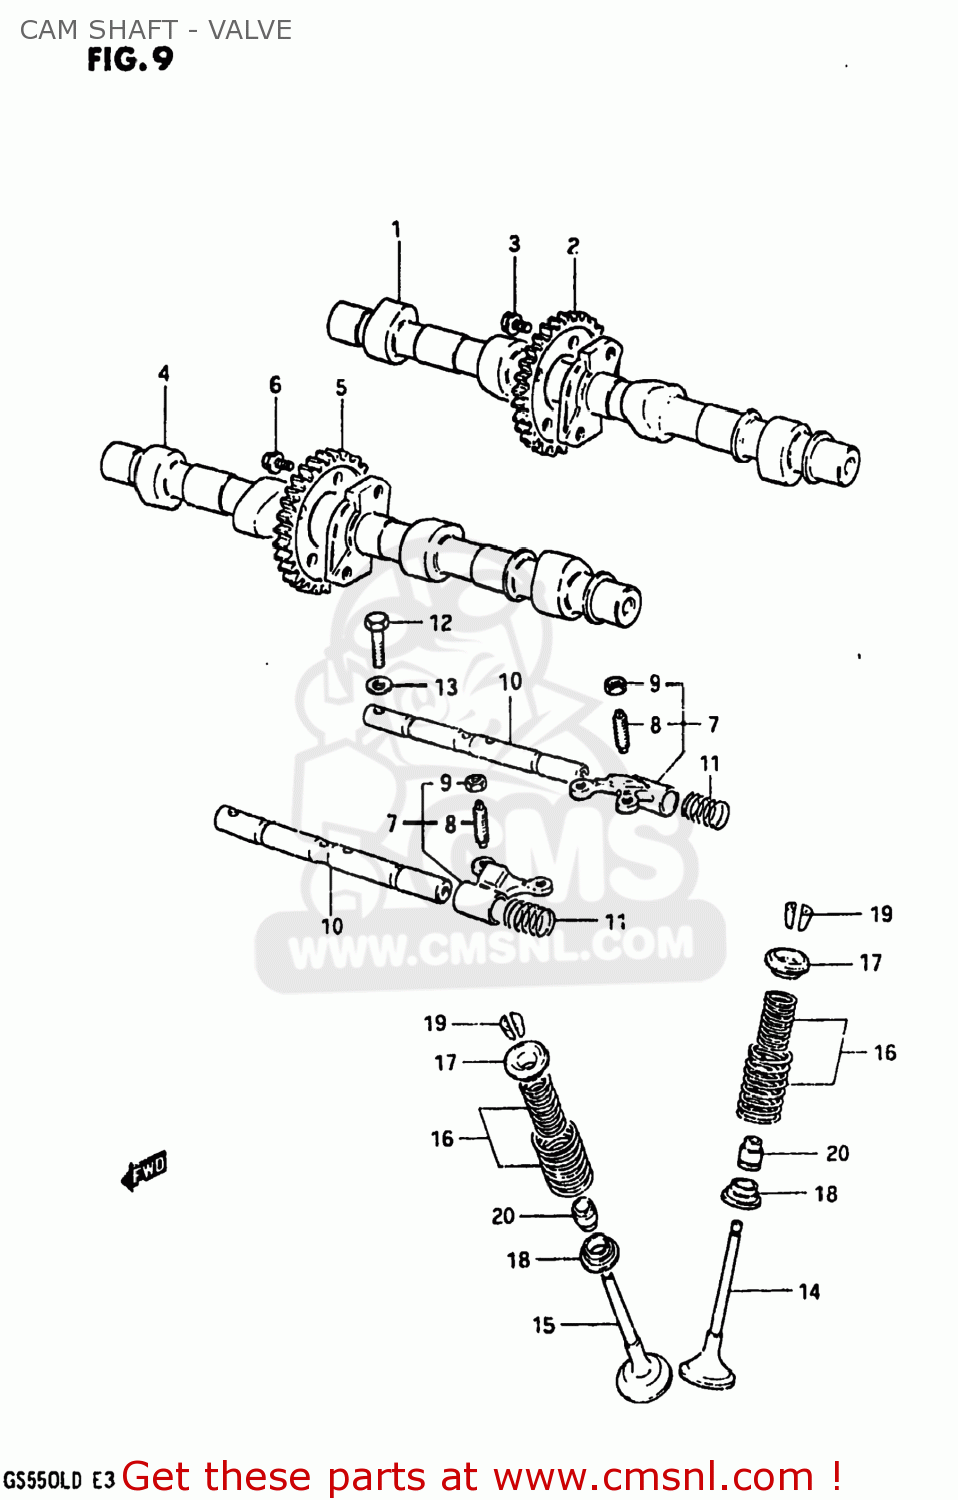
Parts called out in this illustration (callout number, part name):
1	CAMSHAFT
2	SPROCKET,INTAKE CAMSHAFT
3	BOLT(7X11)
4	CAMSHAFT,EXHAUST
5	SPROCKET,INTAKE CAMSHAFT
6	BOLT(7X11)
7	ARM,VALVE ROCKER
8	SCREW,TAPPET ADJUSTING
9	NUT,ADJUSTING
10	SHAFT,VALVE ROCKER
11	SPRING
12	BOLT
13	WASHER
14	VALVE,INTAKE
15	VALVE,EXHAUST
16	SPRING SET,VALVE
17	RETAINER,VALVE SPRING
18	SEAT,VALVE SPRING
19	COTTER,VALVE
20	OIL SEAL
